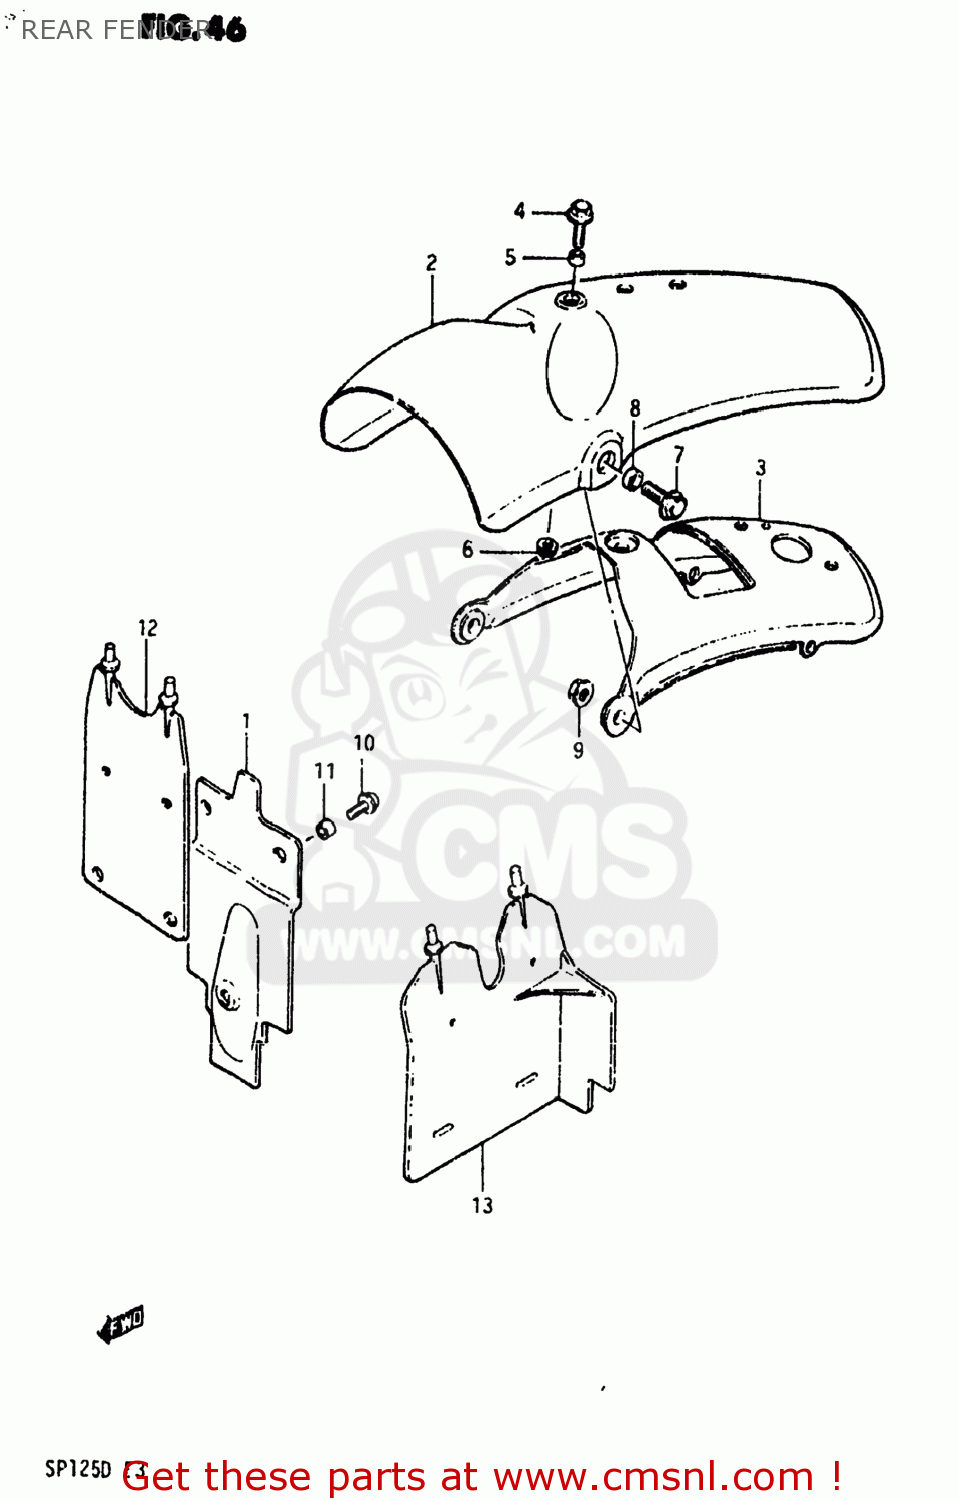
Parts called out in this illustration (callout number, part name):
1	REAR FENDER,FRONT
2	FENDER,REAR
3	REINFORCEMENT,REAR FENDER
4	BOLT,REAR
5	SPACER
6	NUT
7	BOLT
8	SPACER(8.2X14X4.5)
9	NUT
10	SCREW, FRONT
11	SPACER
12	MUD GUARD,REAR FENDER
13	MUD GUARD
